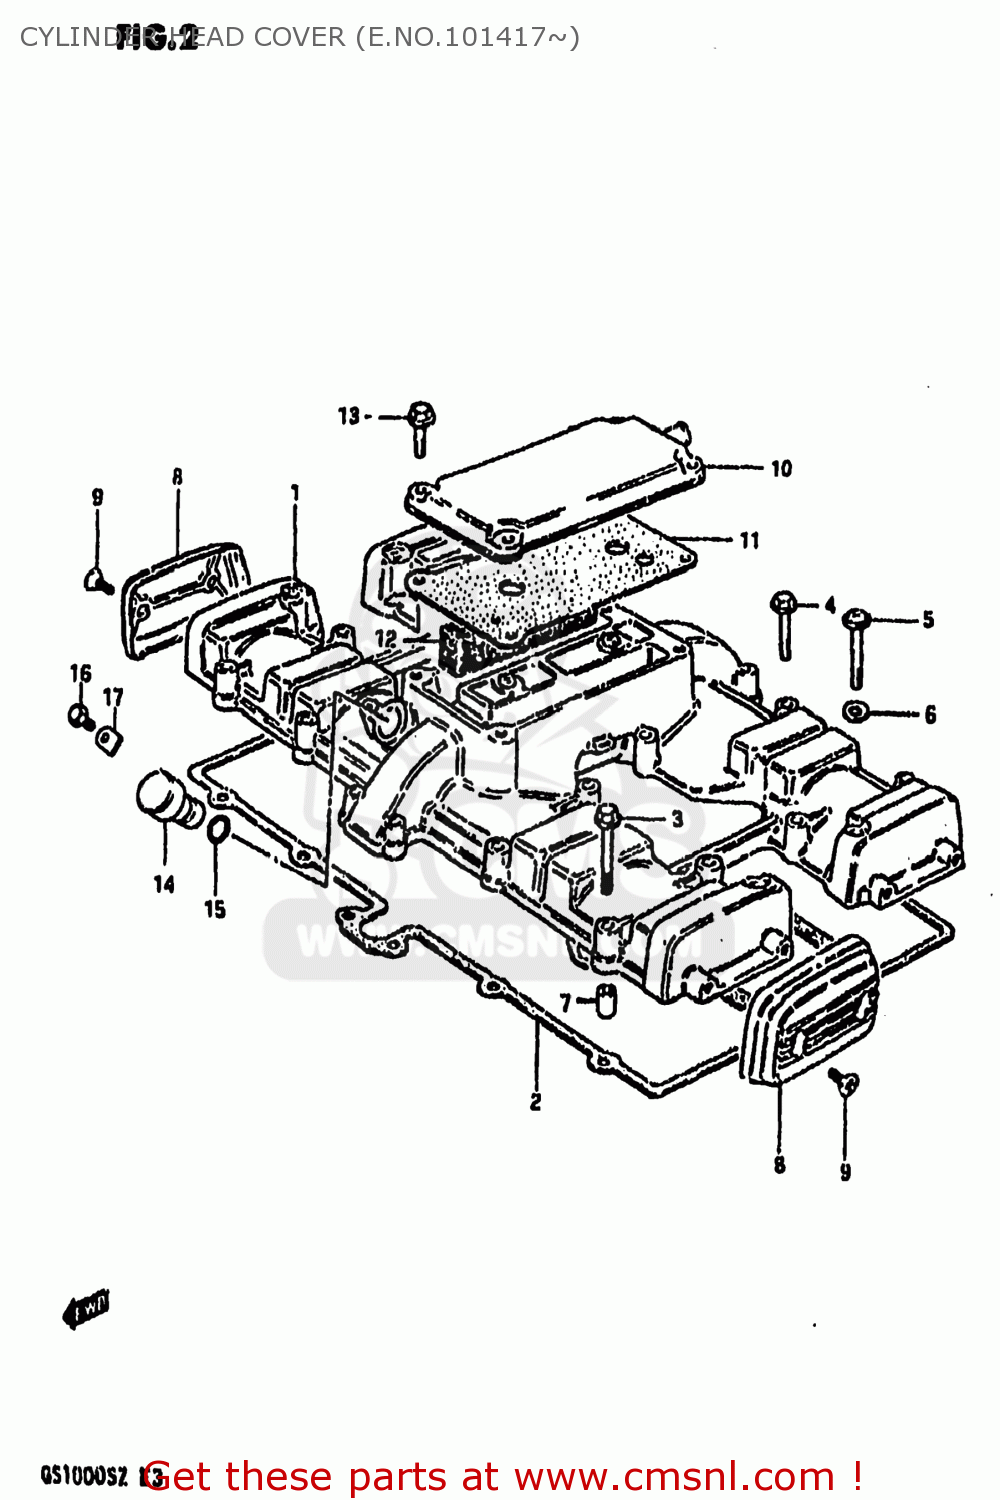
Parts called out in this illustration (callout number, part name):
1	COVER,CYLINDER HEAD
2	GASKET,CYLINDER HEAD COVER (MCA)
3	BOLT
4	BOLT 6X35
5	SCREW 6X40
6	GASKET (NAS)
7	PIN(6.2X8X11)
8	CAP,CYLINDER HEAD COVER
9	SCREW(5X12)
10	COVER,BREATHER
11	GASKET (MCA)
12	COVER,BREATHER
13	BOLT,REAR
14	PLUG,TACH GEAR SLEEVE HOLE
15	SEAL,TACHOMETER DRIVEN
16	SCREW(5X12)
17	PLATE,TACH DRIVE GEAR SLEEVE
